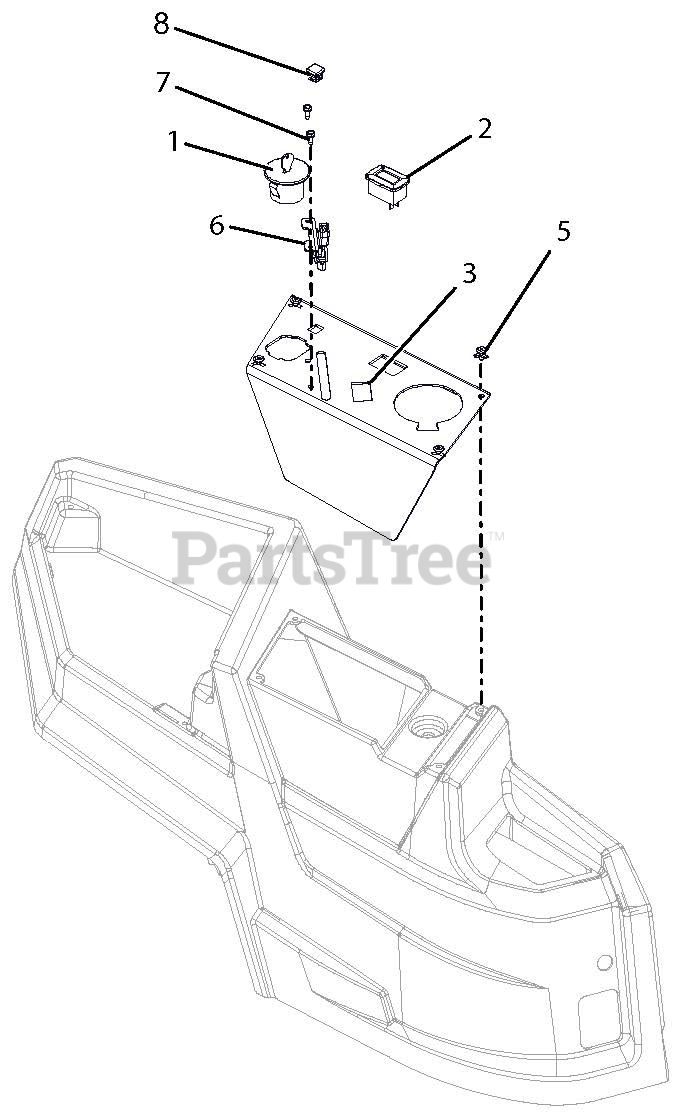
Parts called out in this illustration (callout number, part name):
1	KEY, 03290500 KEYSWITCH
2	METER, HOUR W/MAINTENANCE
3	PANEL, CONTROL
5	RVT-POP .195 PLASTIC
6	CABLE, THROTTLE LH 90DEG 33"
7	SCR-TAP 10-24X.50 HWH TR YWZC
8	PLUG, 5/8" SQ BLACK
